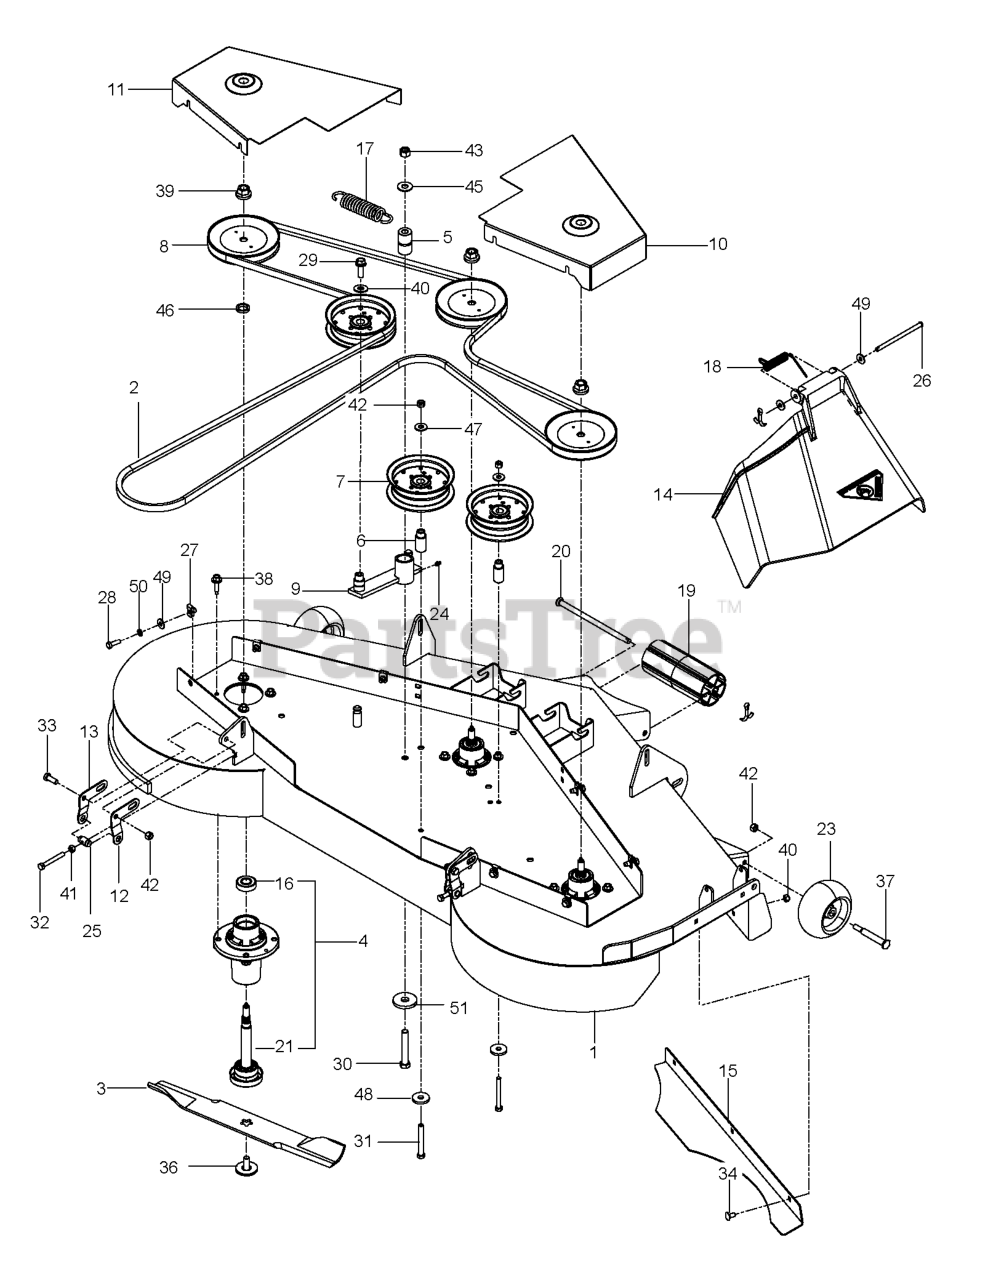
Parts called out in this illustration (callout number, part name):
1	DECK.SVC.W/DECALS.61".EZ.ORANG
2	BELT, DECK
3	BLADE, 21"
4	MANDREL ASM, CAST IRON
5	PIVOT BUSHING
6	IDLER BUSHING
7	PULLEY, IDLER
10	BELT SHIELD, RH ORANGE
11	BELT.SHIELD.LH.ORANGE
12	BRACKET.RT.PNT.MS431
13	BRACKET.LH.PNT.MS431
14	DISCHARGE CHUTE 61"
15	CONFINEMENT PLATE 61
18	SPRING - TORSION
19	NOSE ROLLER 48"
20	ROD.ROLLER.NOSE.NARROW.48"
21	SHAFT ASM MANDREL
23	WHEEL GAGE DONUT
24	ZERK
25	TRUNION, PITCH
26	PIN-CLEVIS 5/16 DIA X 5.19 ZD
27	U-CLIP 5/16-18 NUT RETAINER
28	HCS 5/16C X 3/4
29	4CS 3/8C X 1 SERRATED HEAD
30	HCS 1/2C X 3 1/4
31	BOLT.HEX.FIN.3/8-16 X 3.GR5
32	HCS 5/16-18 X 2 1/2 TPBLT
33	HCS 3/8-16X1.GRD.5.ZD
34	CARRIAGE BOLT 5/16C X 5/8"
36	BOLT.WASHER.ASM.7/16-2
37	BOLT, SHOULDER
38	BOLT.HEX.WASHR.HED.313-18X1.19
39	NUT.FLANGE.LOCK.TOP
40	NUT 5/16 NYLOC
41	NUT 5/16C HEX
42	NUT 3/8-16 NYLOC
43	NUT 1/2-13 HEX NYLOC ZD
45	WASHER 1/2 FLAT
46	WASHER.SPACER.MANDREL
47	WASHER 3/8 FLAT
48	SPINDLE WASHER
49	WASHER 5/16 FLAT
50	WASH 5/16 DISC SPRING ZD
51	WASHER, SUPPORT
